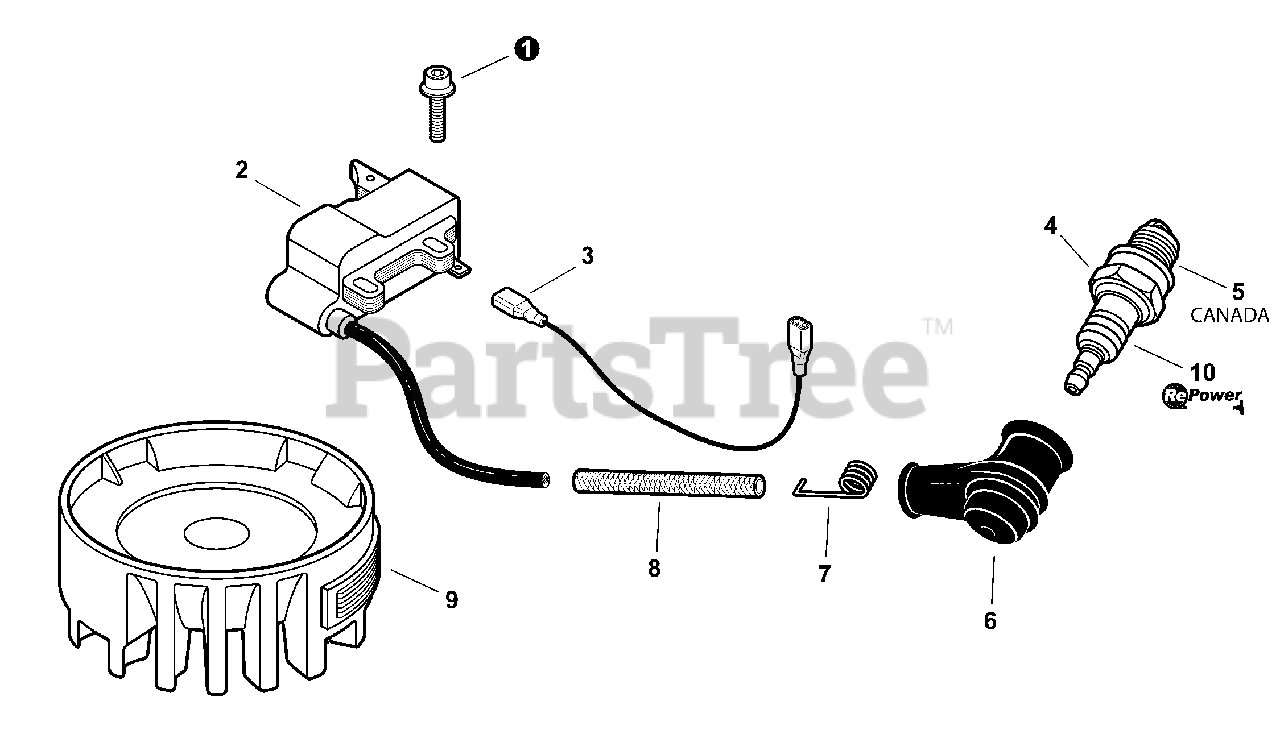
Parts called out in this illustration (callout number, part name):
1	SCREW - 4×20
2	COIL, IGNITION
3	LEAD - IGNITION
4	SPARK PLUG -- BPM8Y
5	SPARK PLUG -- BPMR8Y
6	CAP, SPARK PLUG
7	TERMINAL, SPARK PLUG CAP
8	TUBE, INSULATOR
9	FLYWHEEL
10	RePower TUNE-UP KIT
